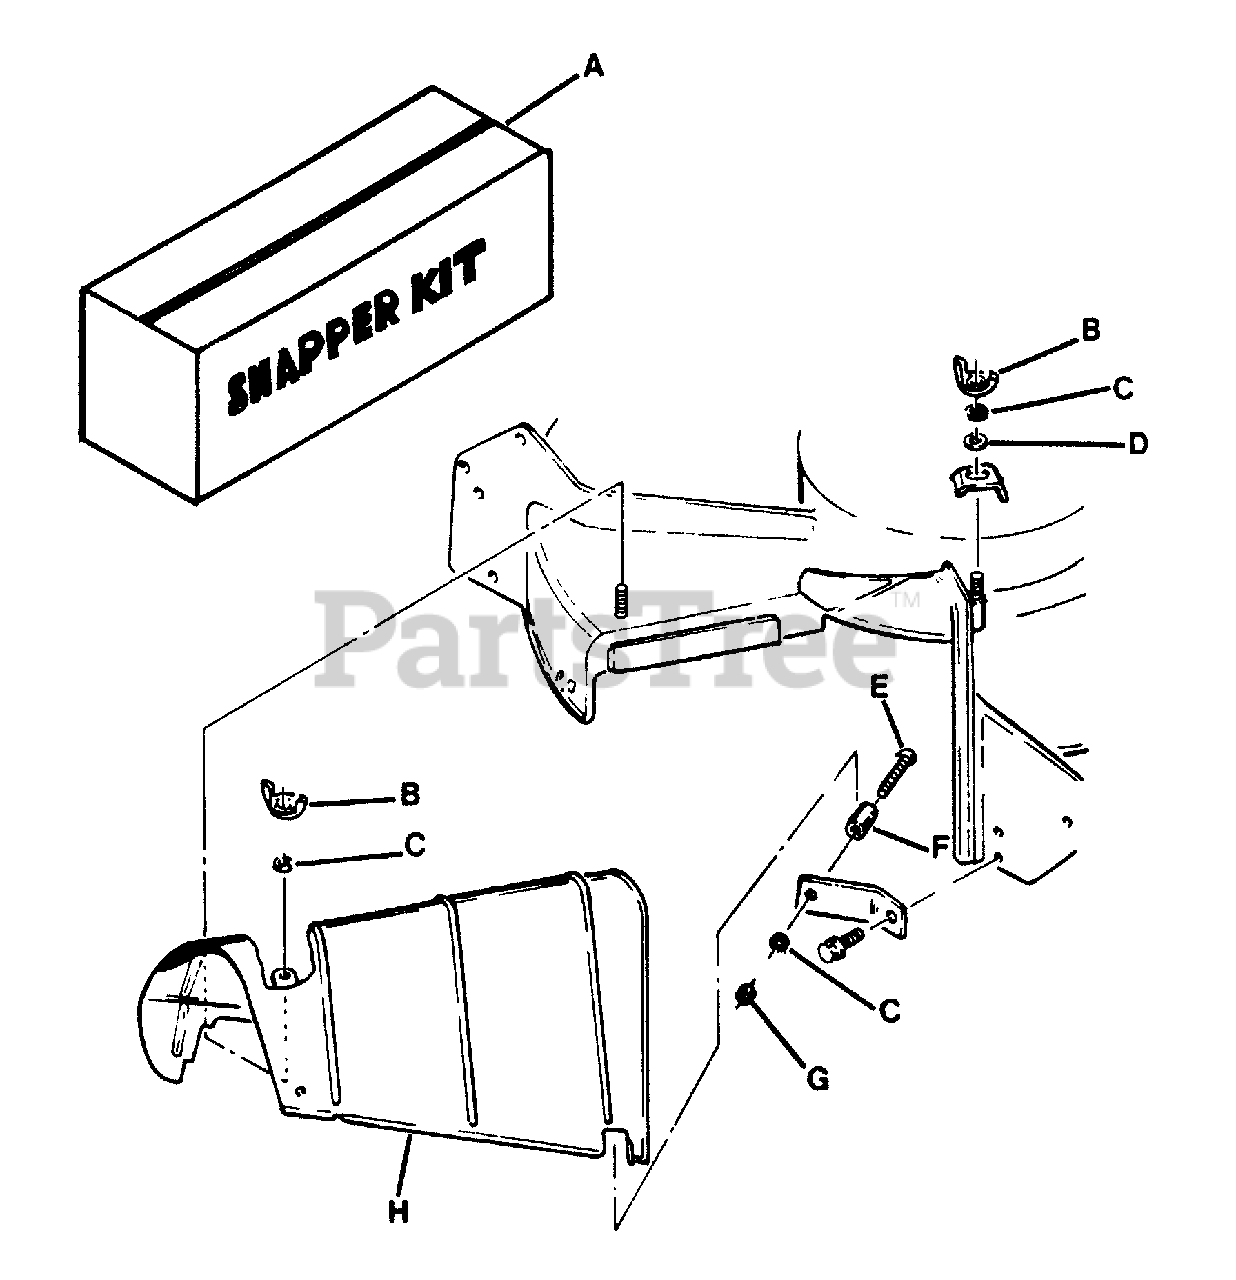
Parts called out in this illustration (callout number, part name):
A	KIT, V18 Side Chute
B	NUT, 5/16-18 Wing
C	WASHER, 5/16 Split Lock
D	WASHER, 5/16 SAE Flat
E	SCREW, 5/16-18 x 1-1/8" Flat Head Countersunk Machine
G	NUT, 5/16-18 Hex
H	CHUTE, V18 Side
